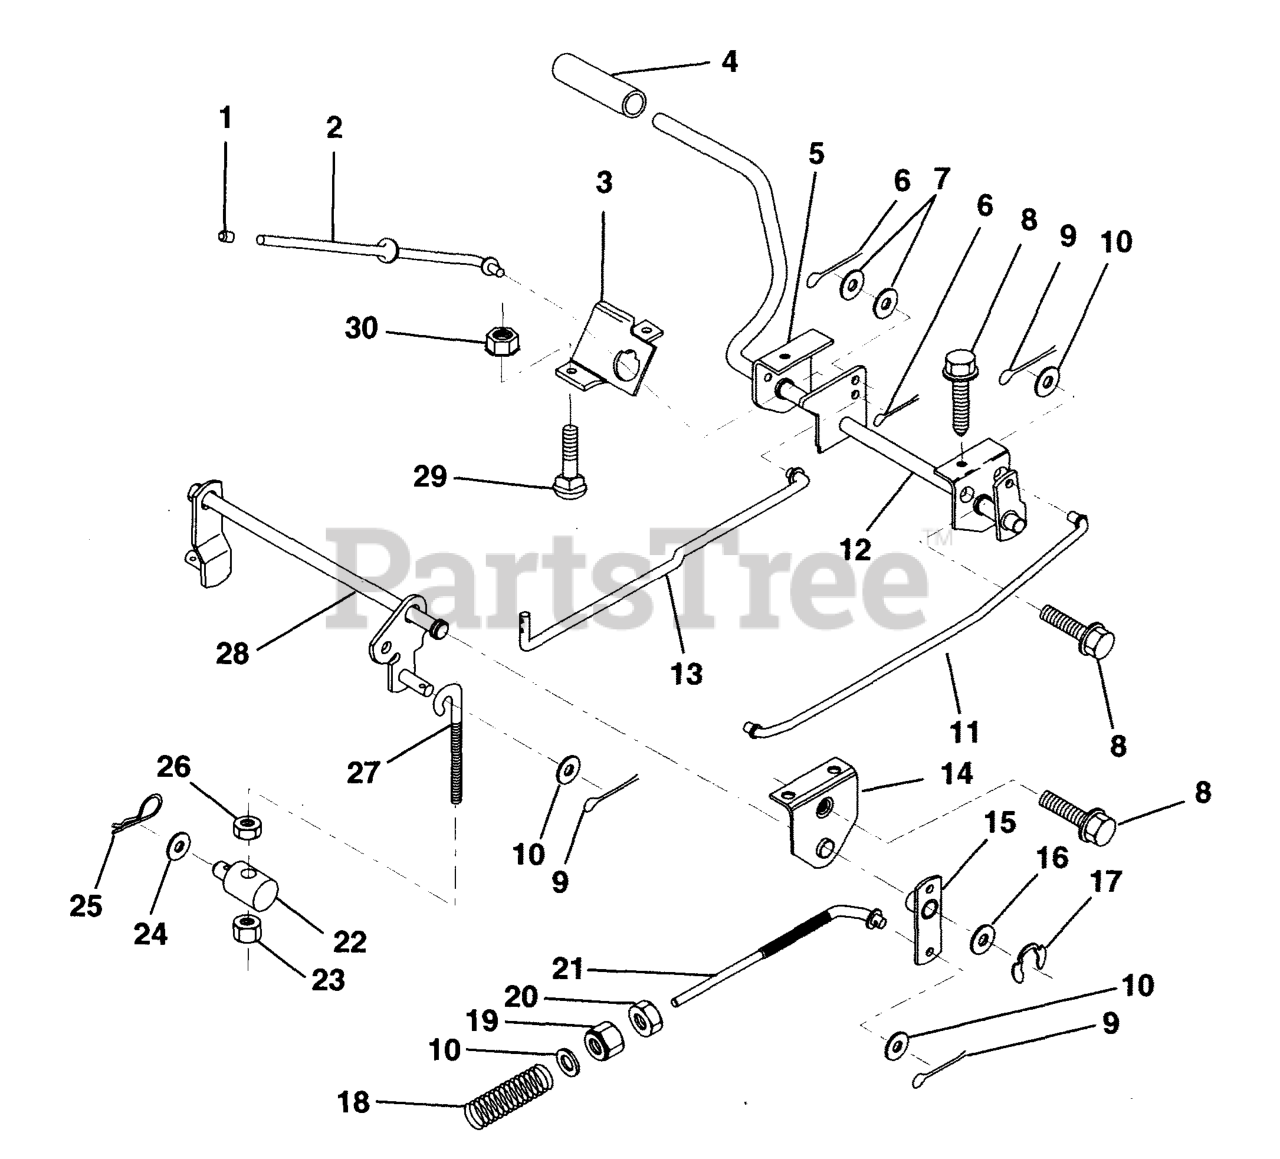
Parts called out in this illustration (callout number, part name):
1	PLUNGER CAP
2	ROD,PARK BRAKE
3	BRKT,PARK BRAKE
4	FOOT PEDAL COVER
5	BRKT,CLU PEDAL LH
6	COTTER PIN
8	Screw, Hex Head, Thd., Roll. 5/16-18 x 1/2
9	COTTER PIN
10	WASHER
11	ROD,FRT BRAKE
12	ASS'Y CLUTCH BRAK
13	ROD,CLUTCH
14	BRKT,LIFT SHAFT
15	BRAKE PIVOT ARM
17	Ring, Klip
18	SPRING ROD LT
19	NUT
20	Nut, Hex, Jam 3/8-16 UNC
22	TRUNION LIFT
24	WASHER
25	SPRING TI
26	LOCKNUT
27	LINK.MOWER.REAR
28	LIFT, REAR
29	BOLT.CARR.SQNK.5/16-18UNC.X3/4
30	NUT
